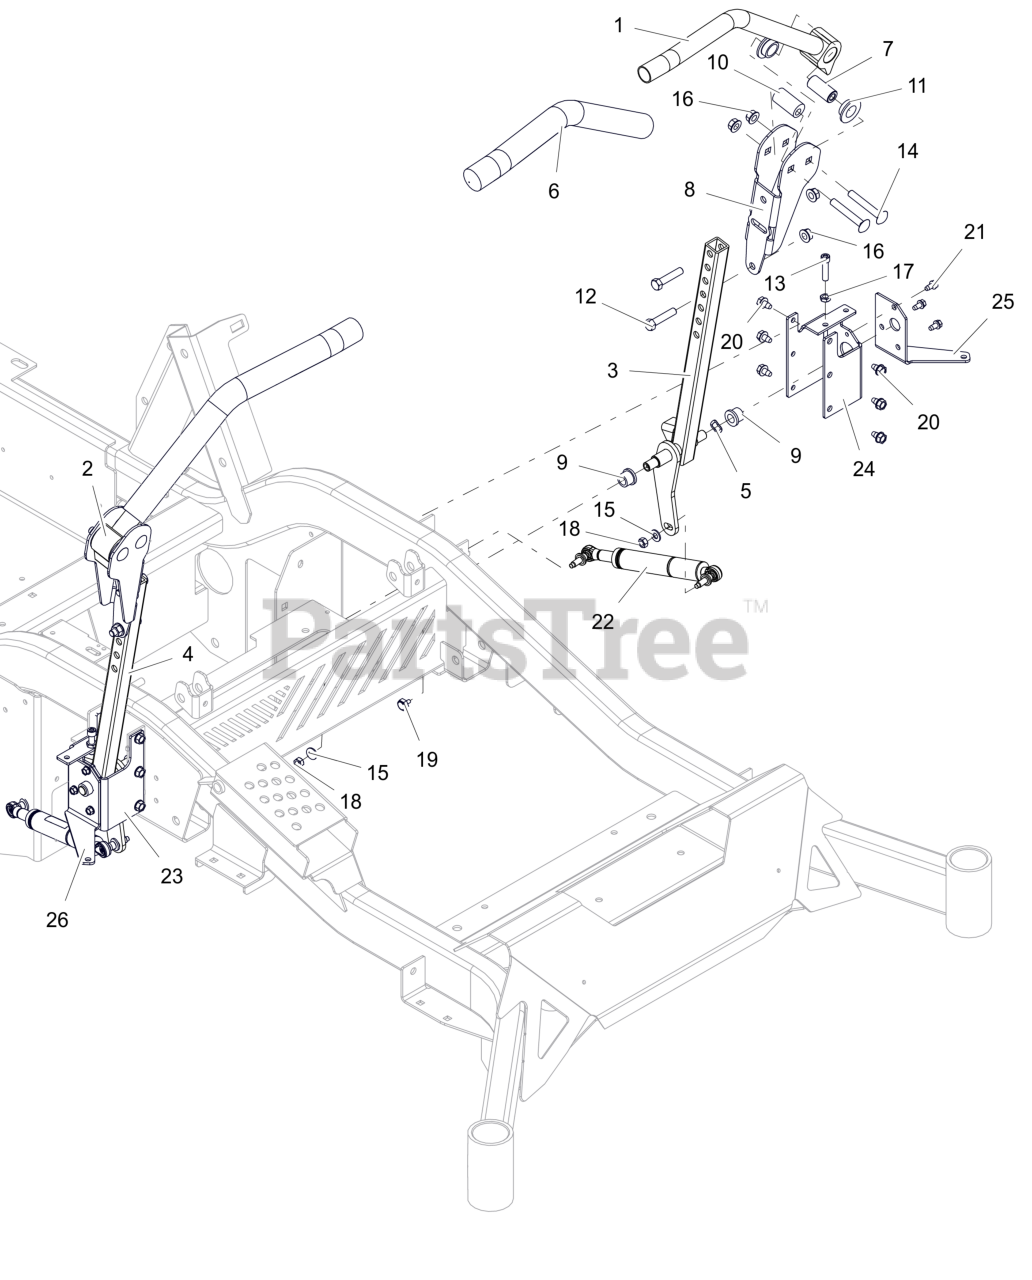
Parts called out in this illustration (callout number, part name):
1	WLDMT, CONTROL HANDLE-LH (BLACK)
2	WLDMT, CONTROL HANDLE-RH (BLACK)
3	WLDMT, STEERING -LH (BLACK)
4	WLDMT, STEERING RH (BLACK)
5	WAVE WASHER .531X.781X.125FH
6	GRIP, HANDLEBAR
7	SPACER, STEERING ARM
8	ADJ UPPER CONTROL ARM BRKT-BLK
9	BSHG, FLG .516X.750X.625X.937
10	BSHG, ECCENTRIC.406X.875X1.625
11	BSHG-FLG .762X1.48X.44 NYL
12	BLT, HEX .38-16X1.75 G5 ZCC
13	BLT, SHCS .312-18X1.25 G8 SS
14	BLT, RHSSN.38-16X2.50 G5 ZCC
15	WSHR, HRDN 0.344X0.688X0.065
16	NUT-LK-CTR-FLG .375-16 GF ZCC
17	NUT-JAM .312-18 G2 ZCC
18	NUT, HEX-JAM CTR-LK M8-1.25 ZCC
19	BOLT, MAGNETIC STEERING SENSOR
20	SCR,TAP .312-18X.50 HWH TR ZCC
21	SCR-TAP .25-20X.50 HWH ZCC
22	DAMPER, NEUTRALIZING
23	WLDMT, STEERING MOUNTING- RH (ORANGE)
24	BRKT, STEERING MOUNTING -LH (ORANGE)
25	BRKT, FRONT FENDER MOUNT-LH (BLACK)
26	BRKT, FRONT FENDER MOUNT-RH (BLACK)
